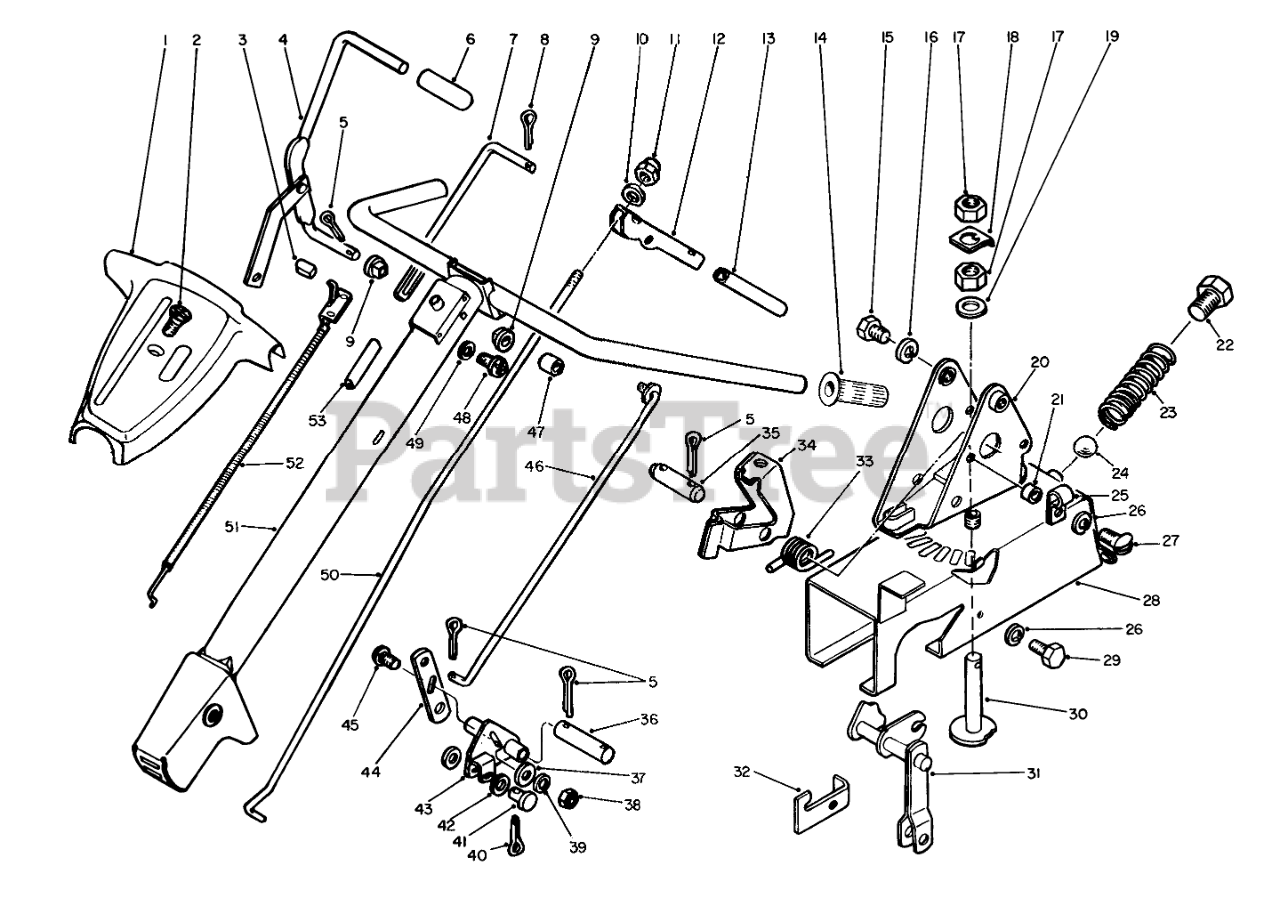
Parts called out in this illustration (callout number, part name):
1	Handle Shroud w/Decal
2	Machine Screw
3	Grip-Throttle Control
4	Control Handle
5	PIN-COTTER
6	Grip
7	Link
8	PIN-COTTER
9	Bushing
10	WASHER-FLAT
11	NUT-LOCK, CONE
12	Lever
14	Grip
15	SCREW-HH
16	WASHER-LOCK
17	NUT-JAM
18	Lock
19	WASHER-THRUST
20	Pivot
21	Spacer-Clamp
22	Hex Hd. Capscrew
23	Spring-Detent
24	Ball-Detent
25	Clamp
26	WASHER-LOCK
27	1/4-20 X 5/8 RD HD SC
28	Tunnel
29	SCREW-HH
30	Plunger
31	Cam Assembly
32	Retainer
33	Spring
34	Pawl
35	Pin
36	Pin
37	Spacer
38	NUT-LOCK, CONE
39	WASHER-LOCK
40	PIN-COTTER
41	Clevis Pin
42	WASHER-FLAT
43	Bellcrank
44	Lever
45	BOLT-CARR
46	Control Rod
47	Spacer
48	Pan Hd. Machine Screw
49	WASHER-LOCK, EXT
50	Control Rod
51	Handle
52	Throttle Control
53	Slide
